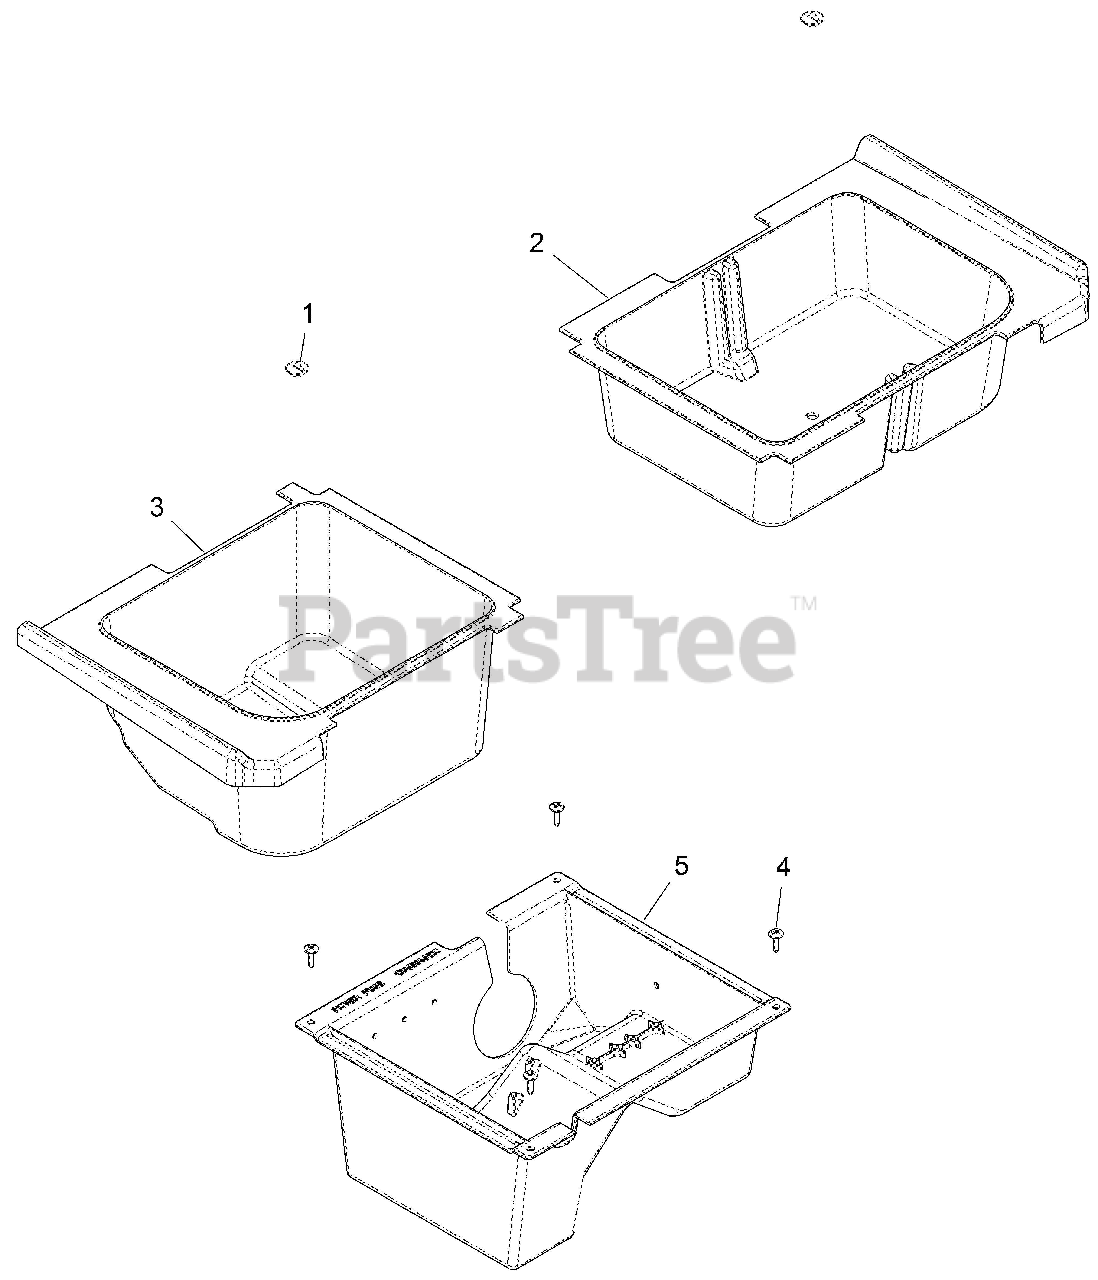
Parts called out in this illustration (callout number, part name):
1	PLUG-COMPARTMENT
2	STORAGE BOX,LH,BLK
3	STORAGE BOX,RH,BLK
4	SCR-TXTH-M6X1.0X25 RIE
5	STORAGE BOX,CENTER,BLK
